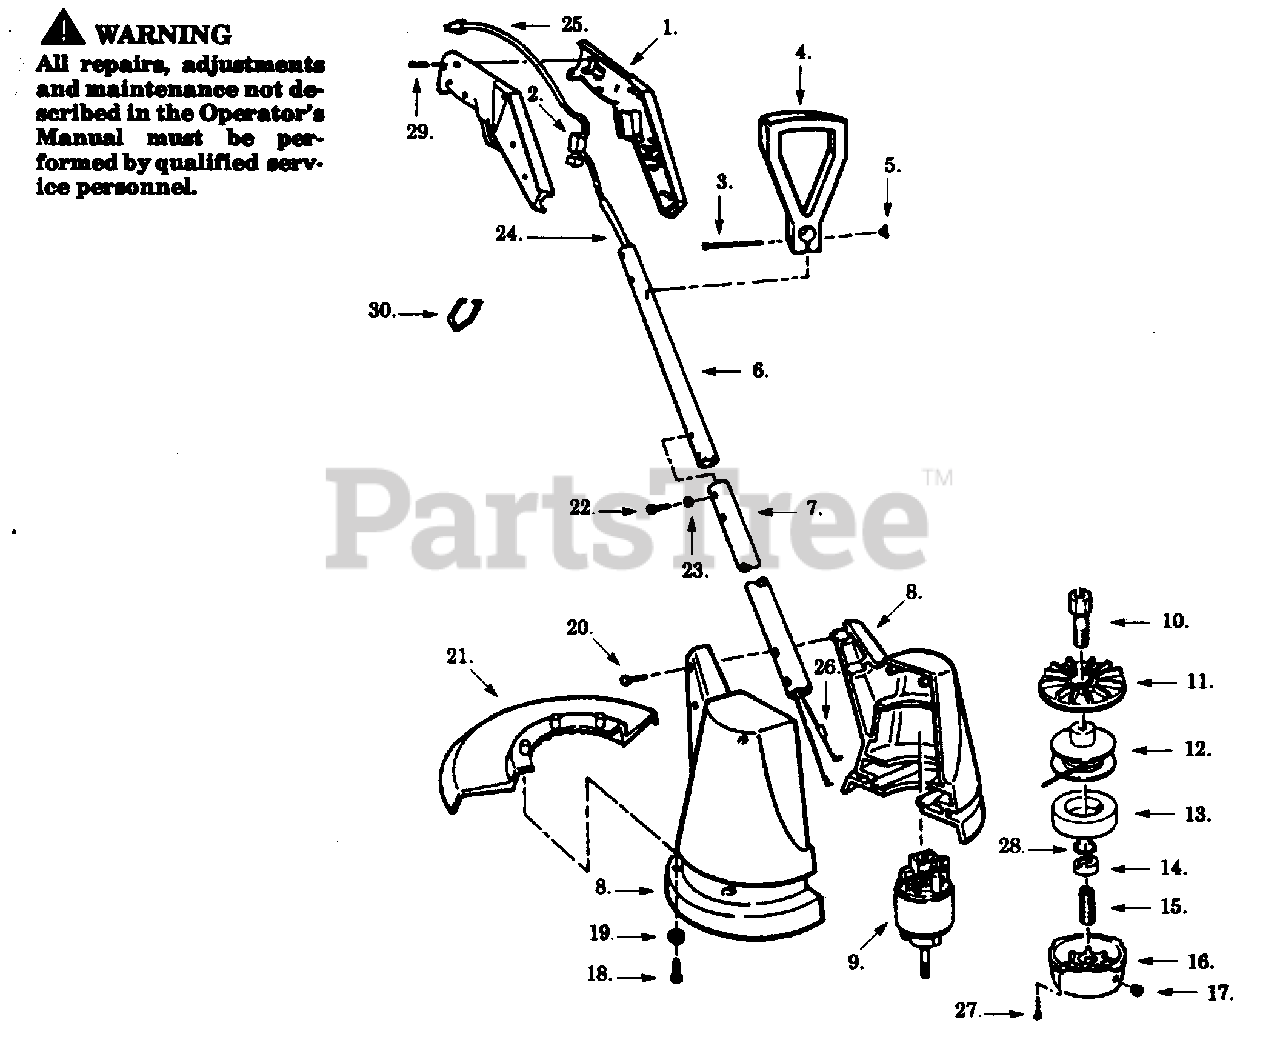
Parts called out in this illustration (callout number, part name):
1	R.H./L.H. Handle
2	Trigger Switch
4	Side Handle
5	Wing Nut
6	Upper Handle Tube
7	Lower Handle Tube
8	R.H./L.H. Housing
10	Drive Adapter
11	Rear Plate
12	Spool & Line
13	Foam Pad
14	Drive Adapter Nut
21	Line Cutter Guard
23	Lockwasher
25	Power Cord
26	Rectifier
27	Cotter Pin
31	Operator Manual
